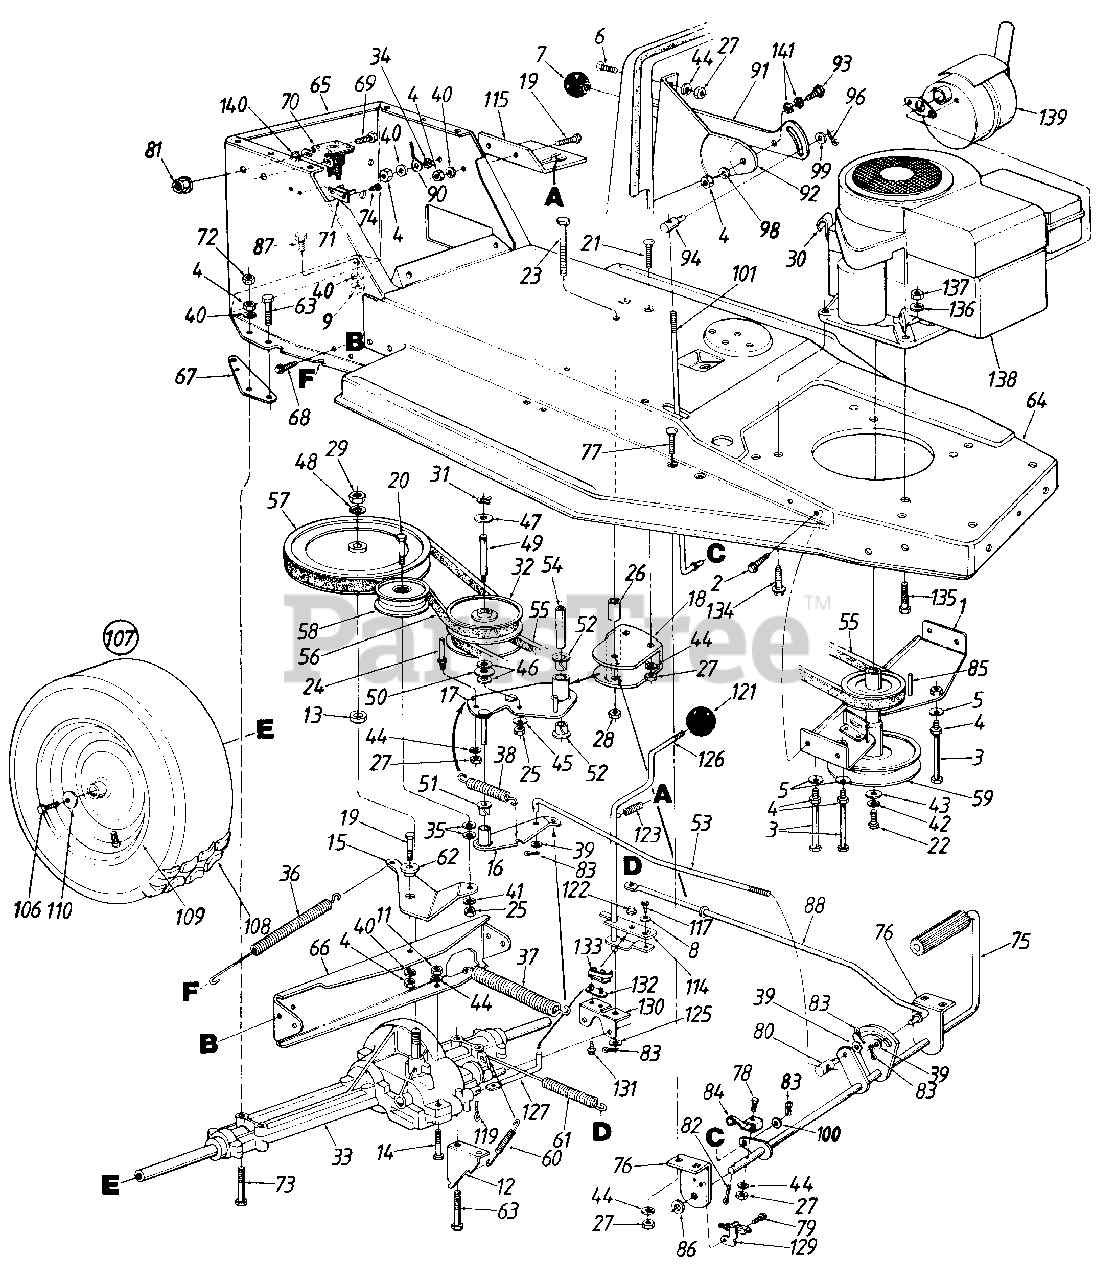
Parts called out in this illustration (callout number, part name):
1	Engine Pulley Belt Guard Ass'y.
2	Hex AB-Tap Scr. 1/4 x .62"
3	Hex Bolt 5/16-18 x 51/4" Lg.
4	Hex Nut 5/16-18 Thd.
5	Bell-Wash. .345" I.D. x .88
6	Truss-Mach. Scr. 1/4-20 x .50" Lg.
7	Shift Knob
8	Bell-Wash. .265" I.D. x .75
9	Hex Nut 5/16-24 Thd.-Gr. 5
11	Hex Nut 1/4-28 Thd.
12	Spring Retainer Brkt.
13	Spacer. 5" I.D.
14	Hex Bolt 1/4-28 x 1.75" Lg.
15	Idler Bracket
18	Variable Speed Pivot Brkt.
19	Hex Bolt 5/16-18 x .75" Lg.
20	Hex Bolt 3/8-24 x 2.0" Lg. Gr. 5
21	Carr. Bolt 1/4-20 x .75" Lg.
22	Hex Bolt 7/16-20 x 1.5" Lg.
23	Hex Bolt 3/8-24 x 4.0" Lg.
24	Belt Guard Pin
25	Hex Nut 3/8-24 Thd.
26	Spacer .38" I.D. x 1.83" Lg.
27	Hex Nut 1/4-20 Thd.
28	Hex Patch Nut 3/8-24 Thd.
29	Hex Jam Nut 1/2-20 Thd.
30	Clamp
31	Snap Ring
32	Variable Speed Pulley Ass'y.
33	Transaxle Complete
34	Ext. L-Wash. 5/16" I.D.
35	Fl-Wash. 3/8" I.D. x 1.0" O.D.
36	Extension Spring 6.12" Lg.
37	Extension Spring 7.5" Lg.
38	Extension Spring 2.59" Lg.
39	Fl-Wash. .385" I.D. x .620"
40	L-Wash. 5/16" I.D.
41	L-Wash. 3/8" I.D.
42	L-Wash. 7/16" I.D.
43	Fl-Wash. .450" I.D. x 1.25"
44	L-Wash. 1/4" I.D.
45	Bell-Wash. .39" I.D. x 1.13"
46	Fl-Wash. .56" I.D. x 1.0" O.D.
47	Washer "Teflon" .565 I.D.
48	Bell-Wash. 1/2" I.D. x 1.0" O.D.
49	Shaft .56" Dia. x 3.875" Lg.
50	Thrust Brg. 1.25 O.D.
51	Flanged Nyliner Brg.
52	Nyliner Flanged Brg.
53	Speed Control Link
54	Spacer
55	V-Belt
56	V-Belt
57	1/2 V-Pulley .500" I.D. x 8.00"
58	Idler Pulley 3-1/8" Dia.
59	Dbl. Pulley 6.0" Dia. x 3.56"
60	Extension Spring 3.18" Lg.
61	Extension Spring 7.08" Lg.
62	Shld. Spacer .500" Dia.
63	Hex Bolt 5/16-18 x 2.75" Lg.
64	Front Frame
65	Rear Frame
66	Transaxle Support Brkt.
69	Hex Bolt 1/4-20 x .62" Lg.
70	Solenoid
71	Circuit Breaker
72	Hex L-Nut 5/16-18 Thd.
73	Hex Bolt 5/16-18 x 3.0" Lg.
74	Truss Mach. B-Tap Scr. #10 x.50" Lg.
75	Clutch/Brake Pedal Ass'y.
76	Clutch/Brake Pedal Mounting Brkt.
77	Carr. Bolt 1/4-20 x .62" Lg.
78	Hex Bolt 1/4-20 x 1.0" Lg.*
79	Hex TT-Tap Scr. 1/4-20 x .5"
80	Ferrule
81	Hex Sems Nut 1/4-20 Thd.
82	Cot-Pin 3/32" Dia. x 1.0" Lg.
83	Cot-Pin 3/32" Dia. x .75" Lg.
84	Switch Actuator
85	Sq. Key 1/4 x 2 0n Lg.
86	Fl-Wash. .635" I.D. x 1.0"
87	Hex Bolt 5/16-24 x .75" Lg.
88	Brake Rod
90	Ground Wire 7.25" Lg.
91	Speed Control Lever
92	5 Speed Selector Brkt.
93	Shld. Bolt .437" Dia. x .35" Lg.
94	Ferrule
96	Intern. Cot-Pin 5/16" Dia.
98	L-Wash. 5/16 I.D.
99	Fl-Wash. .344" I.D. x .62"
100	Fl-Wash. .25" I.D. x .62" O.D.
101	Speed Control Rod
106	Hex L-Bolt 5/16-24 x .75" Lg.
107	Rear Wheel Ass'y. Comp.
110	Bell-Wash. .345" I.D. x .88"
114	Shift Lever Adjusting Link
115	Shift Lever Spring Brkt.
117	Hex Bolt 1/4-20 x .50 Lg.
119	Intern. Cotter Pin
121	Ball Knob
122	Retaining Ring
123	Compression Spring 1.5" Lg.
125	Fl-Wash. .469" I.D. x .88"
129	Safety Switch
130	Shift Lever Support
131	Hex Wash. Hd. #8 x .50" Lg.
132	Insulator Nut Plate
133	Spring Switch
134	Hex Wash. Hd. Tap Scr. 3/8-16 x 1.25" Lg.
135	Hex Bolt 5/16-24 x 11/4" Lg. Grade 5
136	L-Wash. 5/16" I.D.*
137	Hex Nut 5/16-24 Thd.*
138	Engine
139	Muffler
140	Ext. L-Wash. 1/4" I.D.
141	Wave Wash. .445" I.D.
